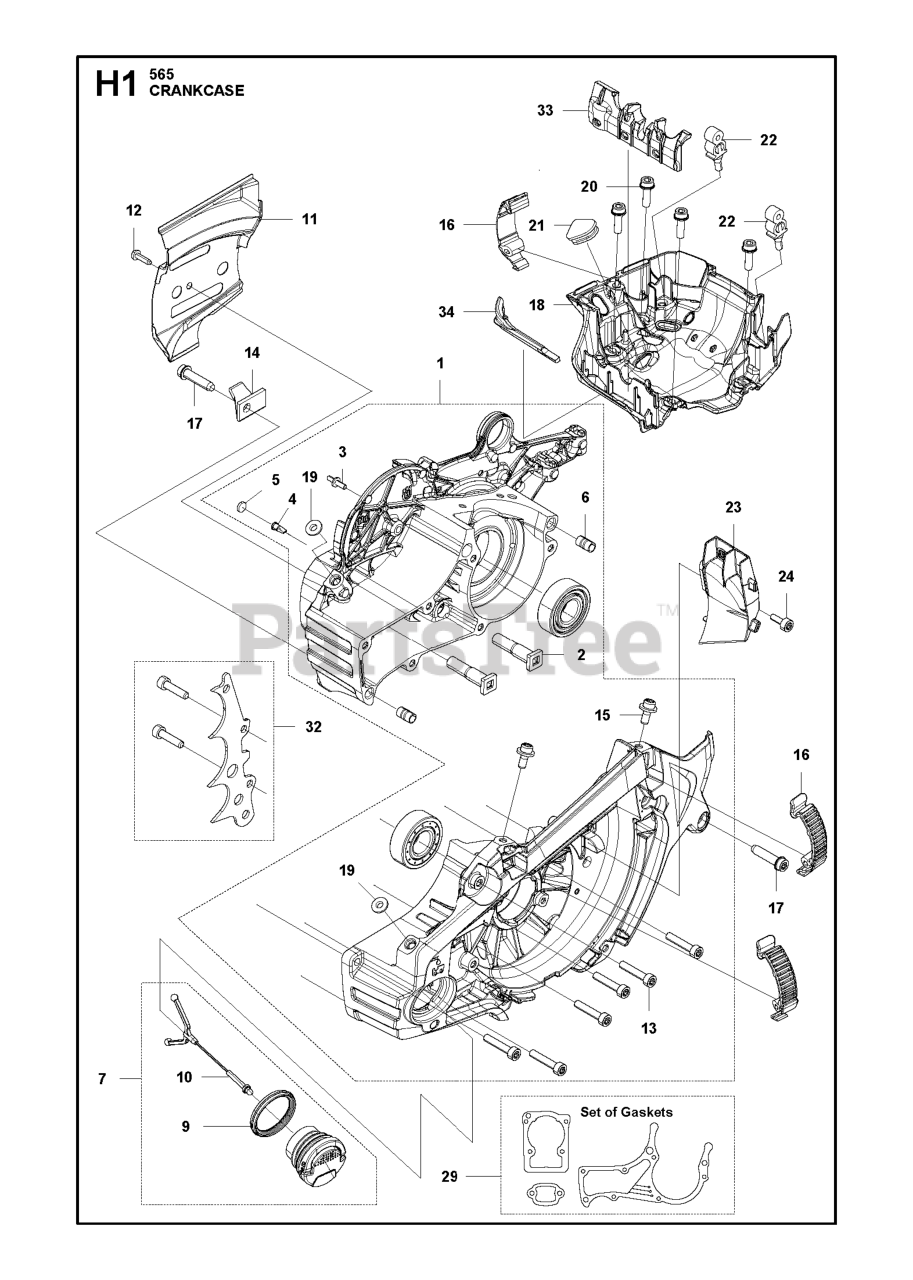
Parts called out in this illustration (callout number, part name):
4	VALVE-CHECK (DUCKBILL)
5	PLUG
6	GUIDE BUSHING
7	TANK CAP ASSY
11	CHAIN GUIDE PLATE BAR MOUNT
13	SCREW ITXSCM M5X25 12.9 TBO T
14	CHAIN CATCHER
15	SCREW ITXSCM WASHER M5X12 T27
16	BUCKLE ORANGE
18	CARBURETTOR AREA BASE ASSY
19	FIXING WASHER DISTANCE WASHER
20	SCREW ITXSCFM
22	SUPPORT
23	AIR NOZZLE
24	SCREW ITXSCM
29	GASKET KIT H565/H572
32	SPIKE KIT - INNER STD H565/H57
33	SEALING CARB AREA BASE
34	SEALING CRANKCASE - CARB AREA
